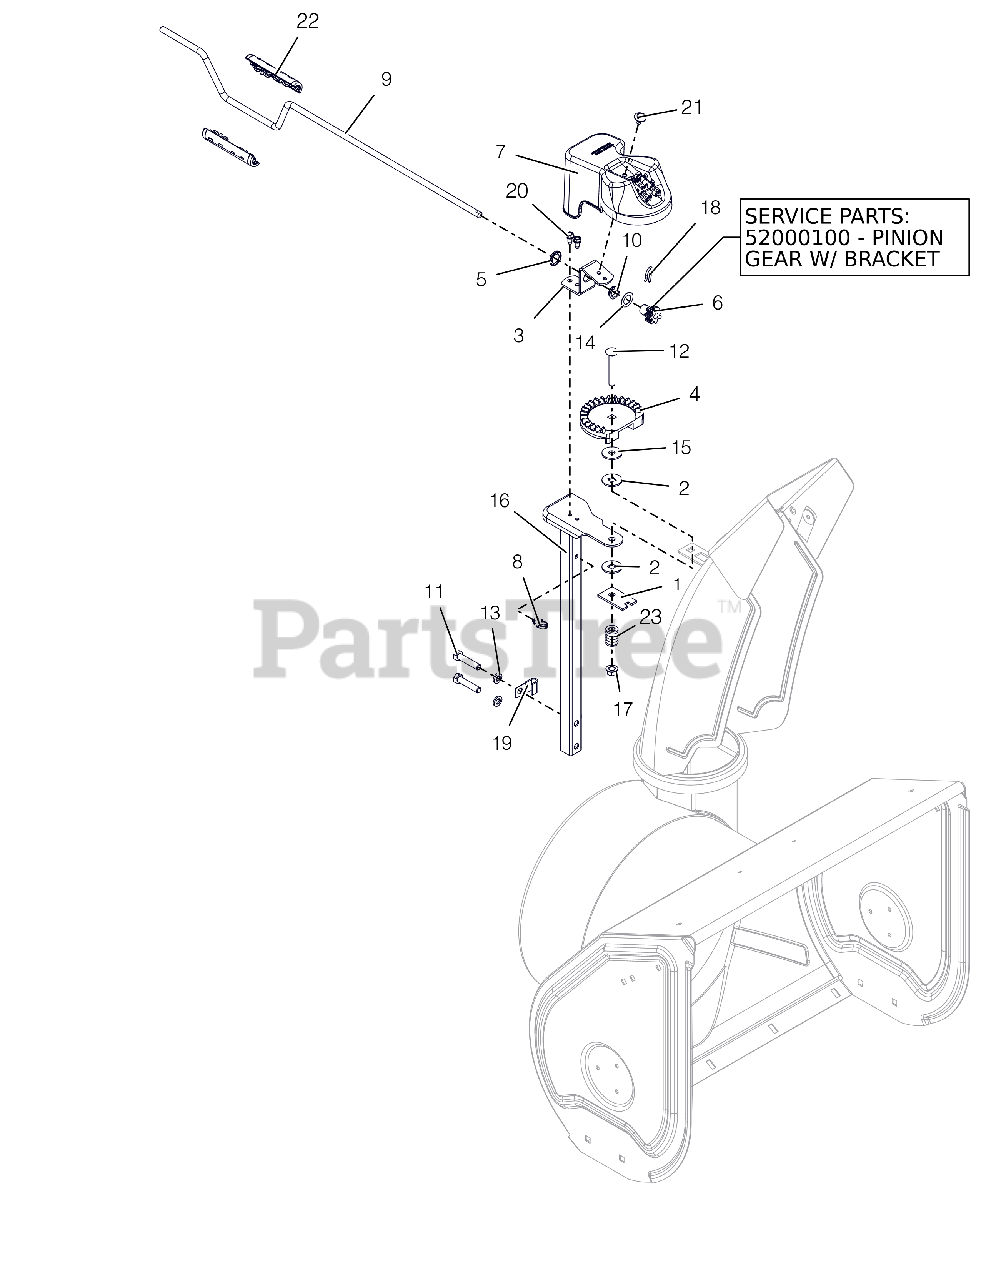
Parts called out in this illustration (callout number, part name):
1	PLATE, FRICTION
2	FRICTION WASHER
3	BRACKET, PINION GEAR
4	CHUTE GEAR
5	PUSHNUT .625
6	PINION GEAR - CHUTE
6	PINION GEAR W/BRACKET
7	GEAR COVER ASSY LG SHEAR BOLT
8	CLIP, CABLE GUIDE
9	ROD,CRANK - SMDASH DLX
10	BUSHING, POLYLINER-.63 SNAPIN
11	@BLT-HEX .38-16X1.75 GR5 YWZC
12	@BLT-RDHDSQNK .38-16X2.50 G5YZ
13	@WSHR-LK .38X.094 REG YWZC
14	WSHR-THRST .625 X 1.0 X .03
15	@WSHR-FL-STL .406X1.25X.10 ZC
16	PEDESTAL, CHUTE - CRANK
17	@NUT-LK-TOP-FLG .38-16 YWZC
18	PIN, SPRING CLIP
19	J-CLAMP
20	SCR-TAP .25-20X.50 HWH TR YWZ
21	SCR-TAP .25-20X.50 LGHWH TR YZ
22	KNOB,CHUTE CRANK-DELUXE
23	SG-COMP .187X.56X1.62
